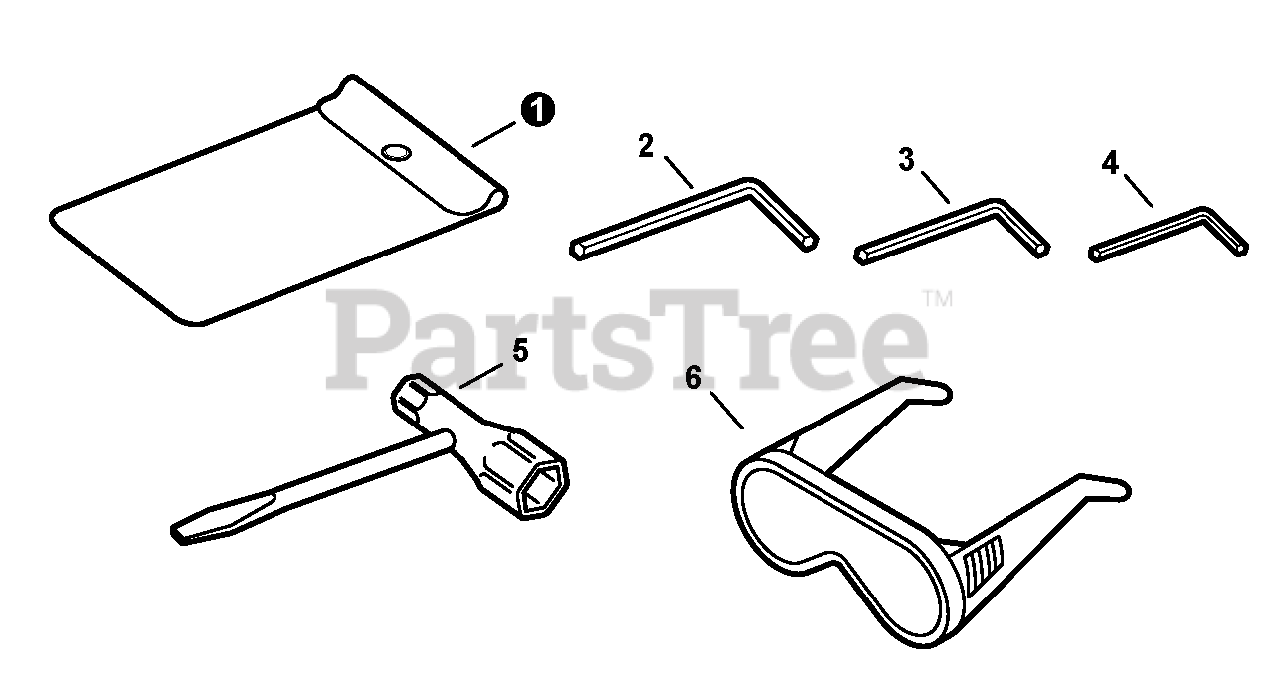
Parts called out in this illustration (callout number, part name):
1	BAG, TOOL
2	WRENCH, ALLEN 5 MM
3	WRENCH, ALLEN 4 MM
4	WRENCH, ALLEN 3 MM
5	T-WRENCH 13×19 MM
6	GLASSES, SAFETY
